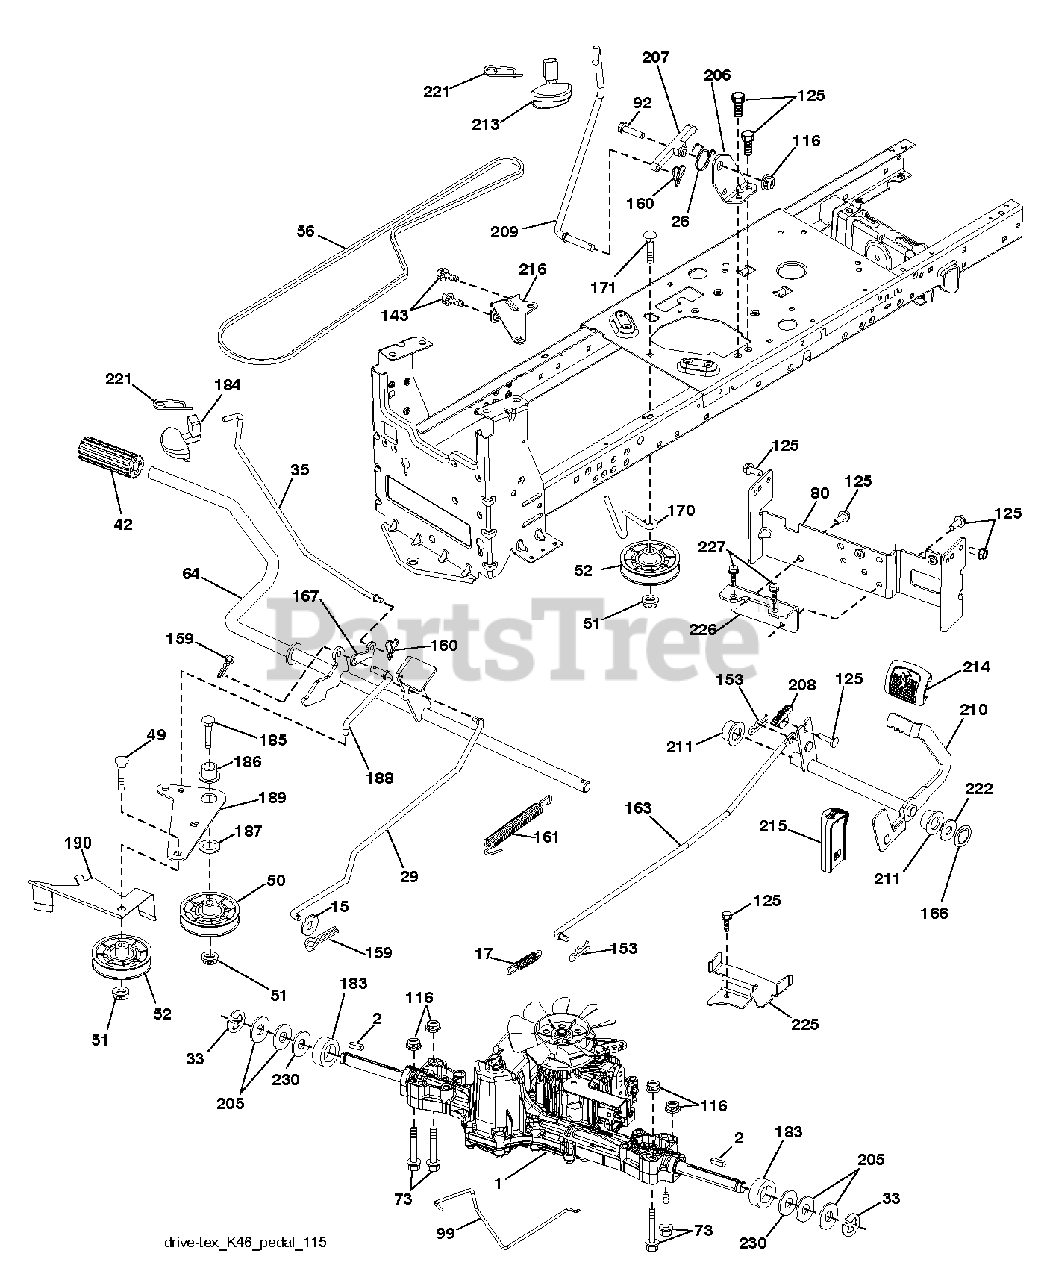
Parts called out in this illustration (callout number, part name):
2	SQUARE KEY
17	SPRING.BRAKE.K46.GREEN
26	SPRING.RETURN.CRUISE
29	ROD.BRAKE.K46
33	E-RING LT
35	ROD.BRAKE.PARKING.LT.T
49	BOLT
50	IDLER.FLAT.910.OFFSET
51	NUT LOCK FLG 3/8-16 UNC
52	IDLER.V-GROOVE.910.OFFSET
56	V-BELT.MOWER.92.40.42/K46
64	SHAFT.ASM.PEDAL.BRK.CNTR
80	STRAP.TORQUE.K46.K57R.TT
92	BOLT
99	ROD.SPRING.BYPASS.K46.LT.Z
116	NUT LOCK HEX FLANGE 5/16-18
125	SCREW
143	SCREW LT
159	COTTER PIN
160	RETAINER CLIP
161	SPRING, RETURN LT
163	ROD.CONTROL.K57R.K46
166	NUT.PUSH.625
167	LATCH.BRAKE.SPRING
170	KEEPER.CENTER SPAN.1.688
171	BOLT
183	SPACER AXLE
184	HANDLE.PARKING.BRAKE.LTTEX.667
186	SPACER.RETAINER
187	WASHER 12/32X2X10GA
188	LINK.CLUTCH.GROUND.DRIVE
189	BELLCRANK.GROUND.DRIVE.TEX.
190	KEEPER.BELLCRANK.DRIVE
206	BRACKET.MOUNT.CRUISE.LATCH
207	LATCH.CONTROL.CRUISE
208	GEAR.SECTOR.CONTROL.CR
210	ROCKER.ASM.PEDAL.CONTR
211	BEARING.NYLON
213	HANDLE.CONTROL.CRUISE.ELTE
214	PEDAL.FORWARD.PAD.TEX
215	PEDAL.REVERSE.TEX.GT.4
216	BRACKET.PULLEY.IDLER.W/TEX
221	RETAINER.SPRING.CLIP.H
222	WASHER 21/32 X 1-1/4 X 10 GA.
225	KEEPER.BELT.TRANSAXLE.K46
226	BRACKET.MOUNT.TORQUE.K46.TLT
227	Screw, Lt
230	WASHER.HARDENED
